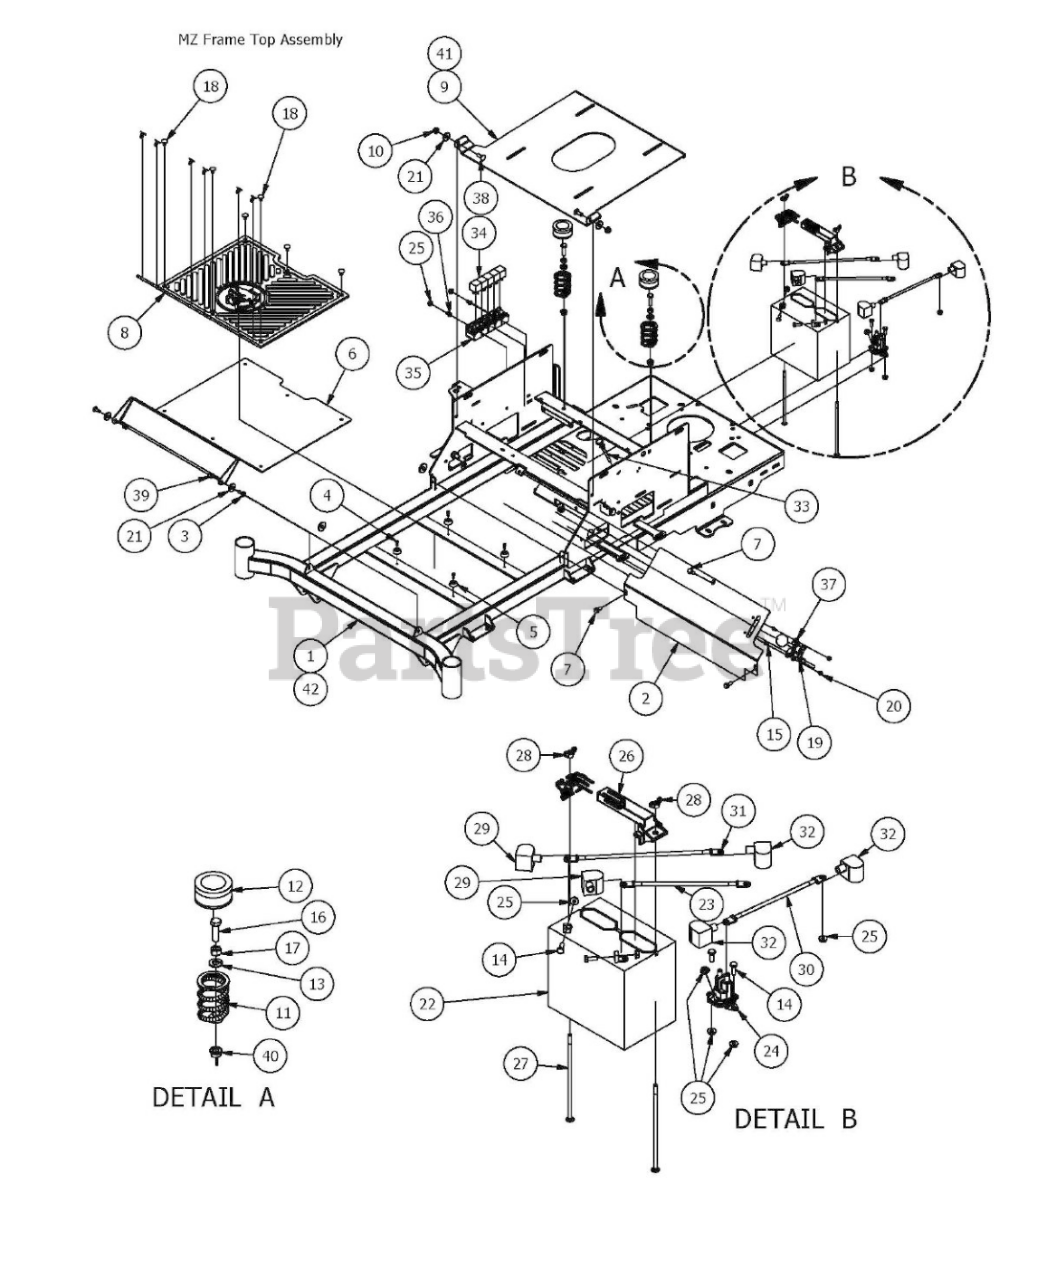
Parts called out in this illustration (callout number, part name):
1	2017 MZ/ZT 42"-48" Frame
2	2017 MZ Cooler Cover
3	1/4" x 3/4" Carriage Bolt
4	#10 x 1/2" Self Tapping Screw
5	Button Bumper
6	MZ/ZT 2017 Floorboard
7	5/16 x 3/4 washer head type F screw
8	2017 MZ/ZT Floor Mat
9	2017 MZ Seat Plate
10	5/16-18 Nylon Flange Nut
11	Seat Spring
12	Seat Spring Cap Cover
13	3/8" Flat Washer
14	1/4" x 3/4" Hex Bolt
15	10-24 x 5/8 Button Head Bolt
16	3/8" x2" Hex Bolt
17	3/8-16 Hex Nuts Zinc
18	5/8" Christmas Tree Fastener
19	MZ Brake Cable
20	10-24 Nylon Insert Locknut
21	.360ID Plastic Washer
23	Ground Cable
25	1/4-20 Hex Flange Nuts Zinc w/Serrations
26	Battery Hold Down
27	1/4-20 X 8 Carriage Bolt
28	1/4" Wing Nut
29	Black Boot For Ground Cable
30	12 in red battery cable
31	24" Red Battery Cable
36	1/4" x 1/2" BS C/S 18-8 SS
37	Universal Throttle
38	5/16" x 7/8" Carriage Bolt
39	1/4-20 Nylon Insert flange Nut
40	3/8" Flange Nut
41	Magnum Seat Pan (Kawasaki Only)
42	Magnum Frame
